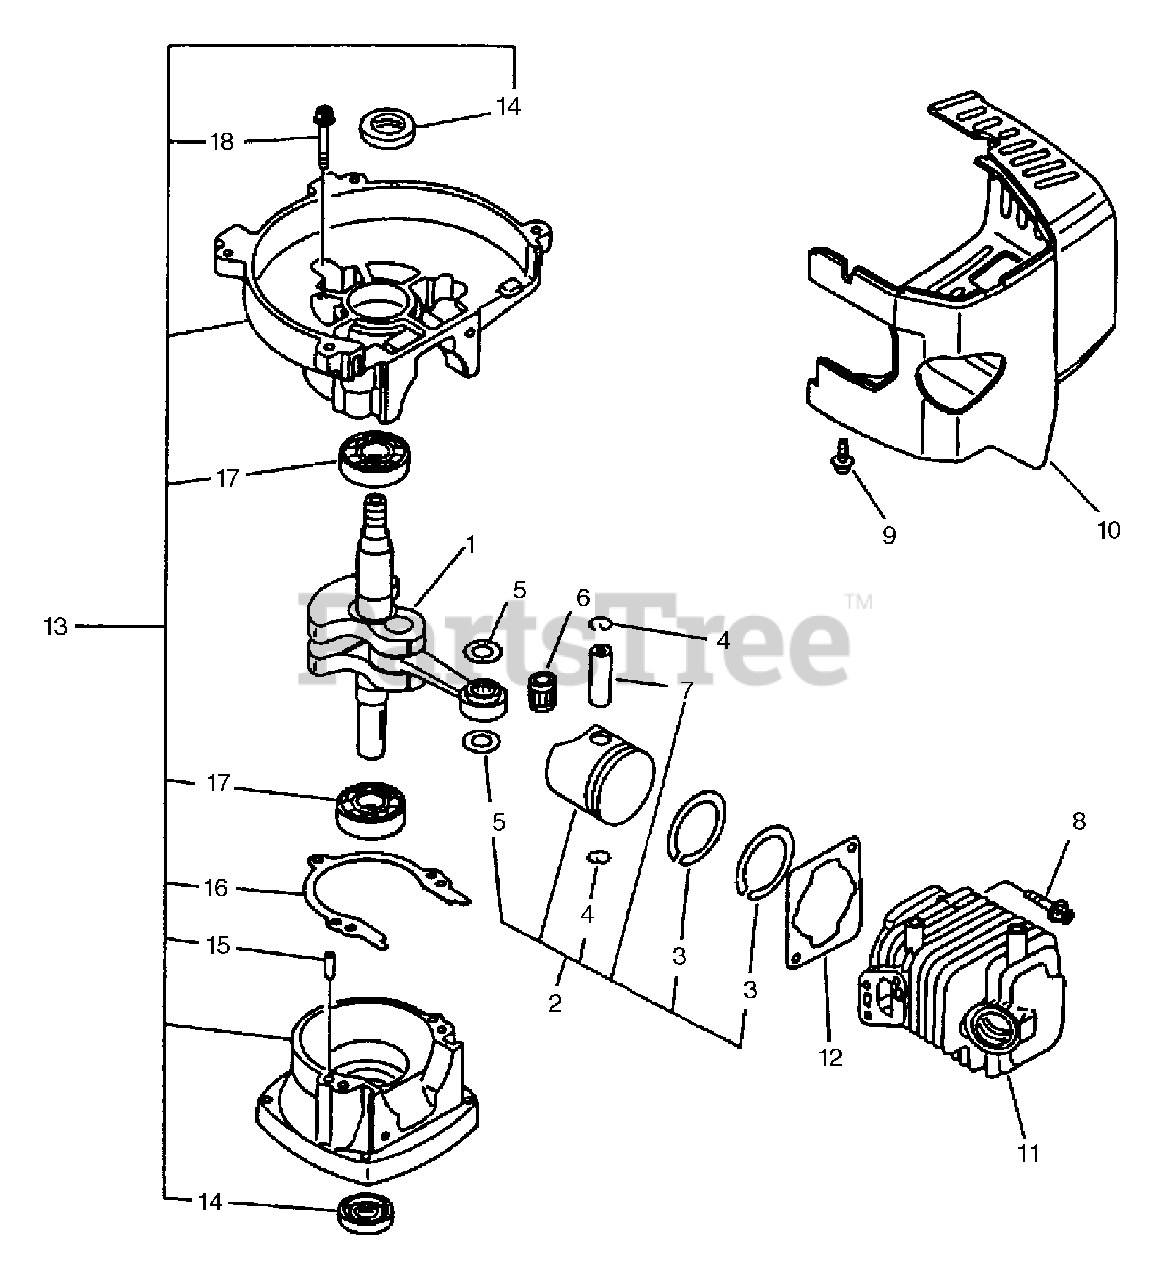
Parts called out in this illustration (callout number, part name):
1	CRANKSHAFT ASSY
2	PISTON KIT
3	RING, PISTON
4	RING, RETAINING
6	BEARING, NEEDLE - 8
7	PIN, PISTON
8	SCREW - 5X22
9	SCREW - 4X20
10	COVER, ENGINE
11	CYLINDER
12	GASKET, CYLINDER
13	CRANKCASE SET
14	SEAL, OIL
15	PIN - LOCATING
16	GASKET, CRANKCASE
17	BEARING, BALL - 6201
18	SCREW - 5X28
